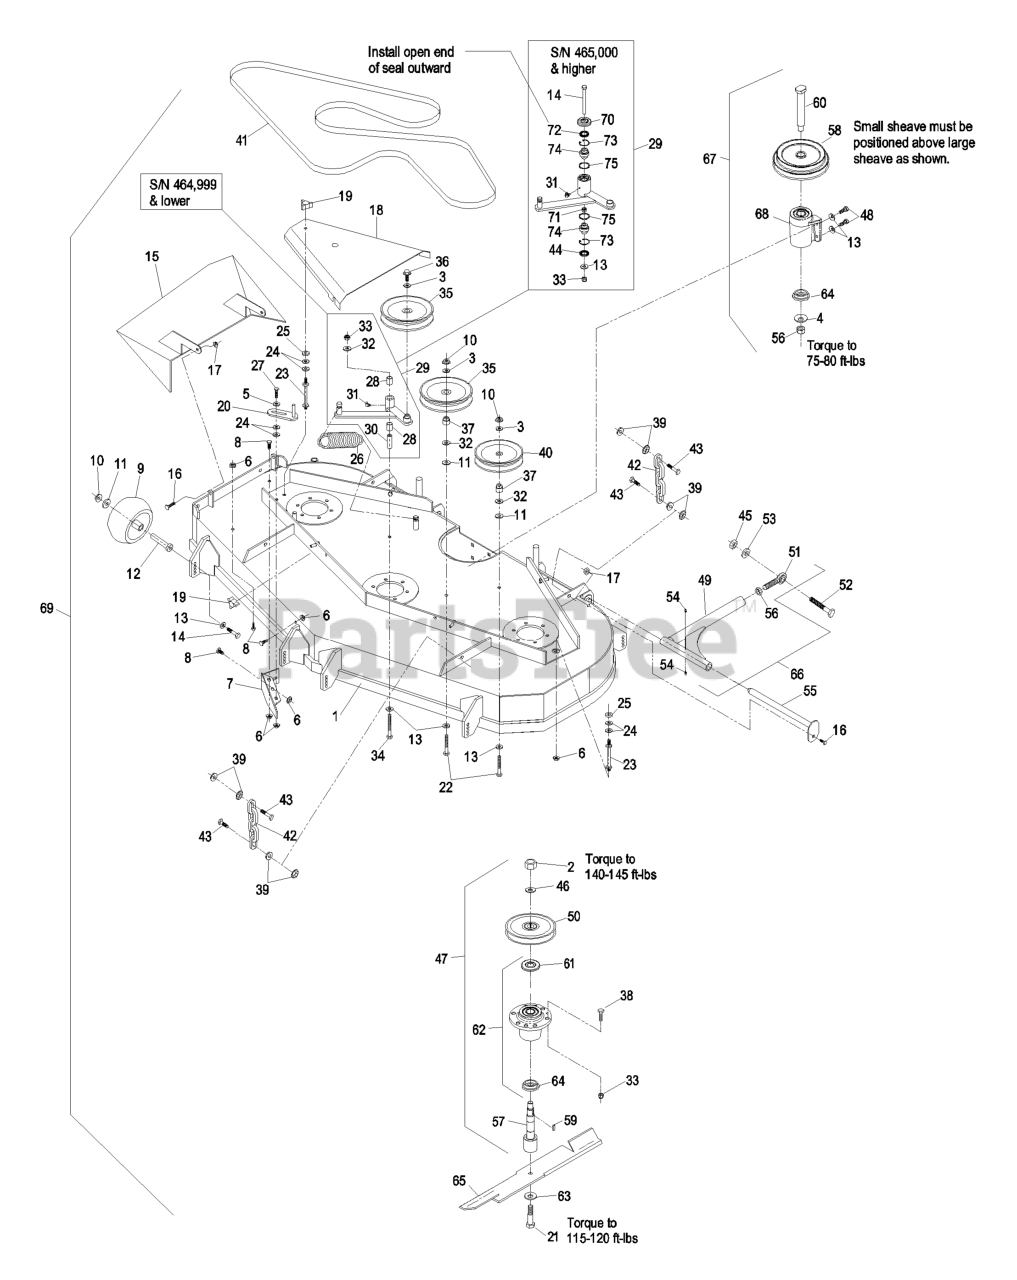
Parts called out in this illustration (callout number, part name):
1	ASM,DECK W/DECALS LZ604
3	WASHER-FLAT
4	WASHER-SPRING
5	WASHER-SPRING
7	WLD,BAFFLE DISCHARGE
8	SCREW-HH
9	ROLLER-SCALP, ANTI
10	NUT-HHF, WHIZ
12	BUSHING-ROLLER
13	WASHER-BELLEVILLE
14	SCREW-HH
15	WLD,CHUTE LZ604
16	SCREW-HH
17	NUT-LOCK, NI
18	SHIELD,BELT
19	KNOB-3 PRONG
20	GUIDE-BELT
21	SCREW-CAP
22	SCREW-HH
23	STUD-SHIELD, BELT (SHORT)
24	WASHER-FLAT
27	SCREW-HH
28	SLEEVE-BEARING
29	KIT,DECK IDLER LZ/XP
30	BUSHING
31	FITTING-GREASE, 90 DEG
32	WASHER-FLAT
33	NUT-LOCK, NI
34	SCREW-HH
36	SCREW-HHF
37	BUSHING-IDLER
38	SCREW-HH
40	PULLEY-IDLER
41	BELT,BLADE DRIVE
42	CHAIN-LIFT, DECK
43	SCREW-HH
44	SEAL-LIP, DOUBLE
45	NUT-HEX
48	SCREW-HH
50	SHEAVE,BLADE DRIVE 6.30
51	BALLJOINT-SPHERICAL
52	SCREW-HH
53	WASHER-LOCK
54	FITTING-GREASE
55	PIN-STRUT
56	NUT-HEX
57	SPINDLE,SHORT
58	SHEAVE, JACKSHAFT DOUBLE
60	JACKSHAFT
61	GUARD-BEARING, TOP
63	WASHER-BLADE BOLT, HEAVY
64	SPACER-GUARD, BOTTOM
66	STRUT ASM
67	KIT,JACKSHAFT 60/72-3750
69	Complete Deck Assy
70	GUARD-TOP
71	SPACER
72	SEAL-LIP, SINGLE
73	RING-SNAP
74	BEARING-SPHERICAL
75	O-RING
